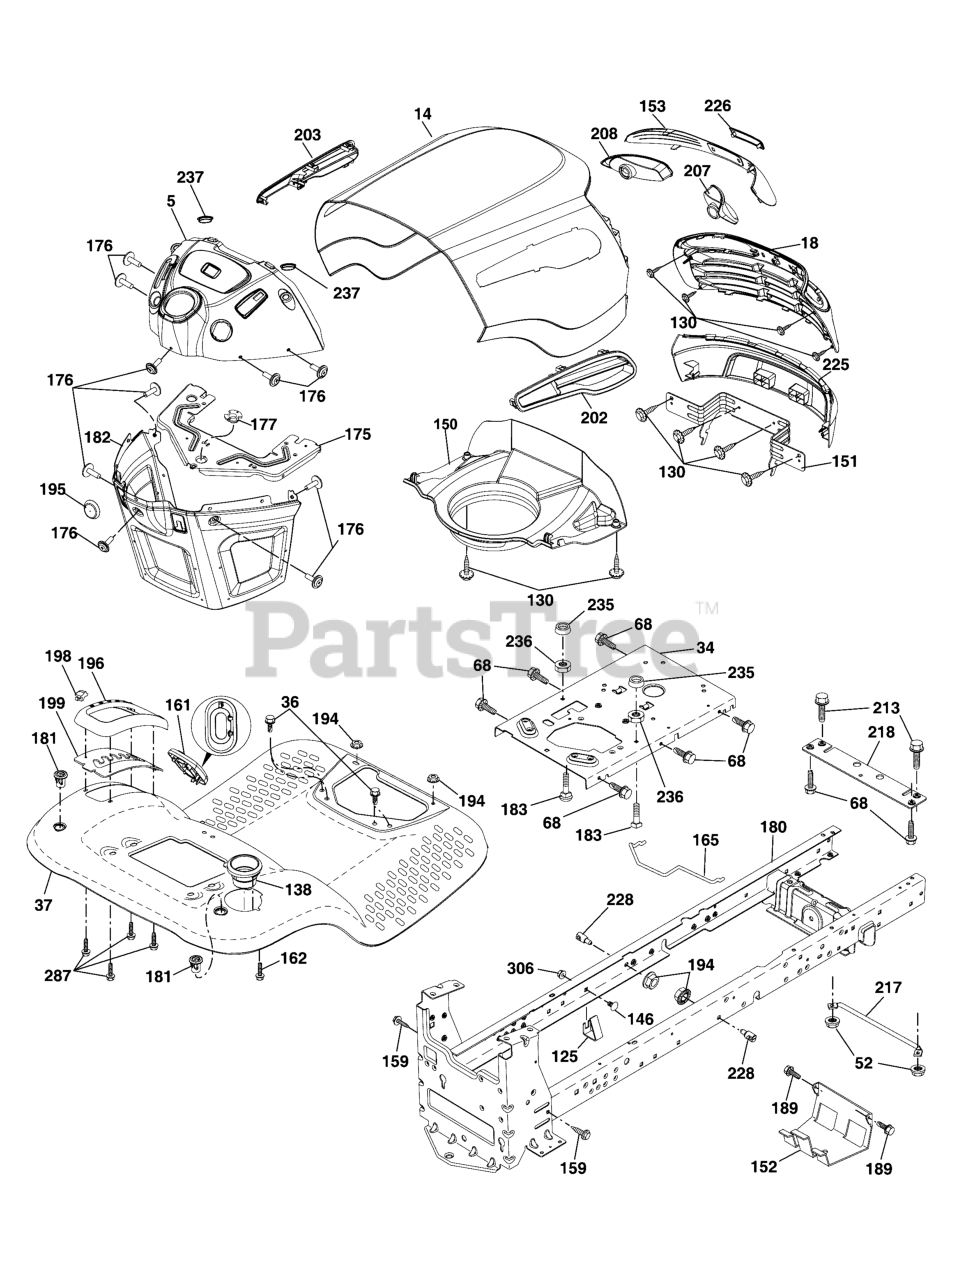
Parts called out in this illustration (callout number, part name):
34	Plate Engine Welded Chassis
36	Screw 5/16-18 X 3/4 Smgml Tap/R
52	Nut, Hex, Crownlock 5/16-18
68	SCREW, 5/16-18 X 1/2, Thread Roll
125	Clip Fuel Line
130	Screw #10 x 0.750 BOS Thread
138	CUPHOLDER
150	DUCT, Air
151	Bracket Pivot Lasr/Elte/Husqlt
152	Shield Browning/Debris
153	LENS, Bar Pred
159	Screw 3/8-16 x .75 Smgml Tap/R.Z
161	Window Fuel
162	Screw Hex Wsh Hi-Lo 1/4 X 1/2 Unc
165	Support Tank Rear
175	CROSSMEMBER
176	Screw #10-24X5/8 Rnd Qudrx Gim
177	Bushing Steering Yt/Gt
180	Chass Wldmt Tl 12 Ga/2Pc
181	Bushing Mnt Fend Crgo Blk Tex
182	DASH, Lower
183	Bolt Full Thd 5/16-18 x 1-1/4
189	Screw 5/16-18 X 3/4 Smgml Tap/Bl
194	Nut, Lock Hex Flange 5/16-18 Unc
195	PLUG, Lower Dash Hole
196	Console Asm. Deck Lift
198	Indicator Deck Lift
199	Plate Deck Lift
202	VENT, RH Side Hood
203	VENT, LH Side Hood
204	VENT, Top
207	BEZEL, RH
208	BEZEL, LH
213	Bolt Hex Hd. 5/16-18 unc x 3/4
217	Rod Pivot Hood
218	X-Piece Hood Stop Non/Stealth
225	BUMPER, Snapper
226	PLATE, Snapper Logo
228	Stud Fastner W/'D'anti-Rotatio
235	Spacer Fender
236	Nut Center Lock 5/16-18 Unc
237	Plug Mount Cargo
287	Screw Hex Washead 1/4-20 X 3/8
306	NUT, 3/8-16, Lock
